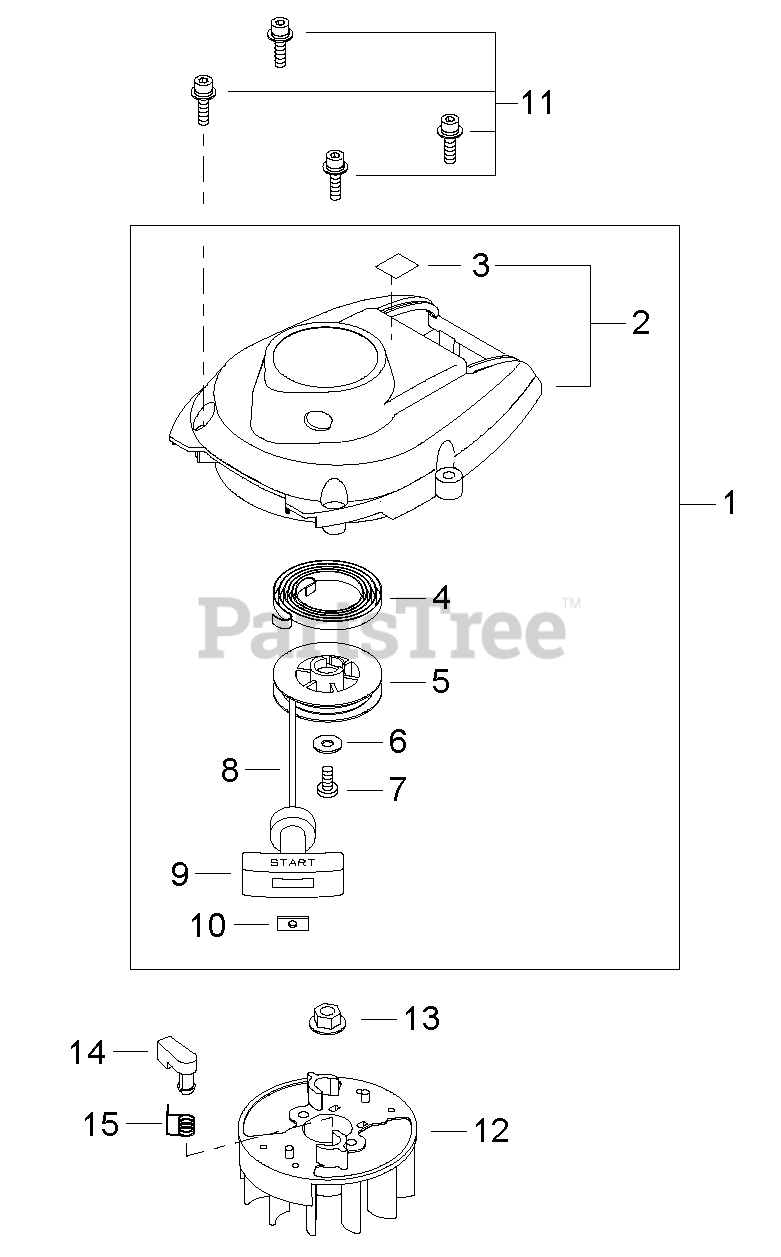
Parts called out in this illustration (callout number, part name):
1	STARTER ASSY
2	STARTER ASSY
3	LABEL - HOT SURFACE
4	SPRING, REWIND
5	REEL, ROPE
6	WASHER - 5
7	SCREW - 5
8	ROPE, STARTER
9	GRIP, STARTER
10	RETAINER, ROPE
11	SCREW - 5X20
12	FLYWHEEL
13	NUT - 8
14	PAWL, STARTER
